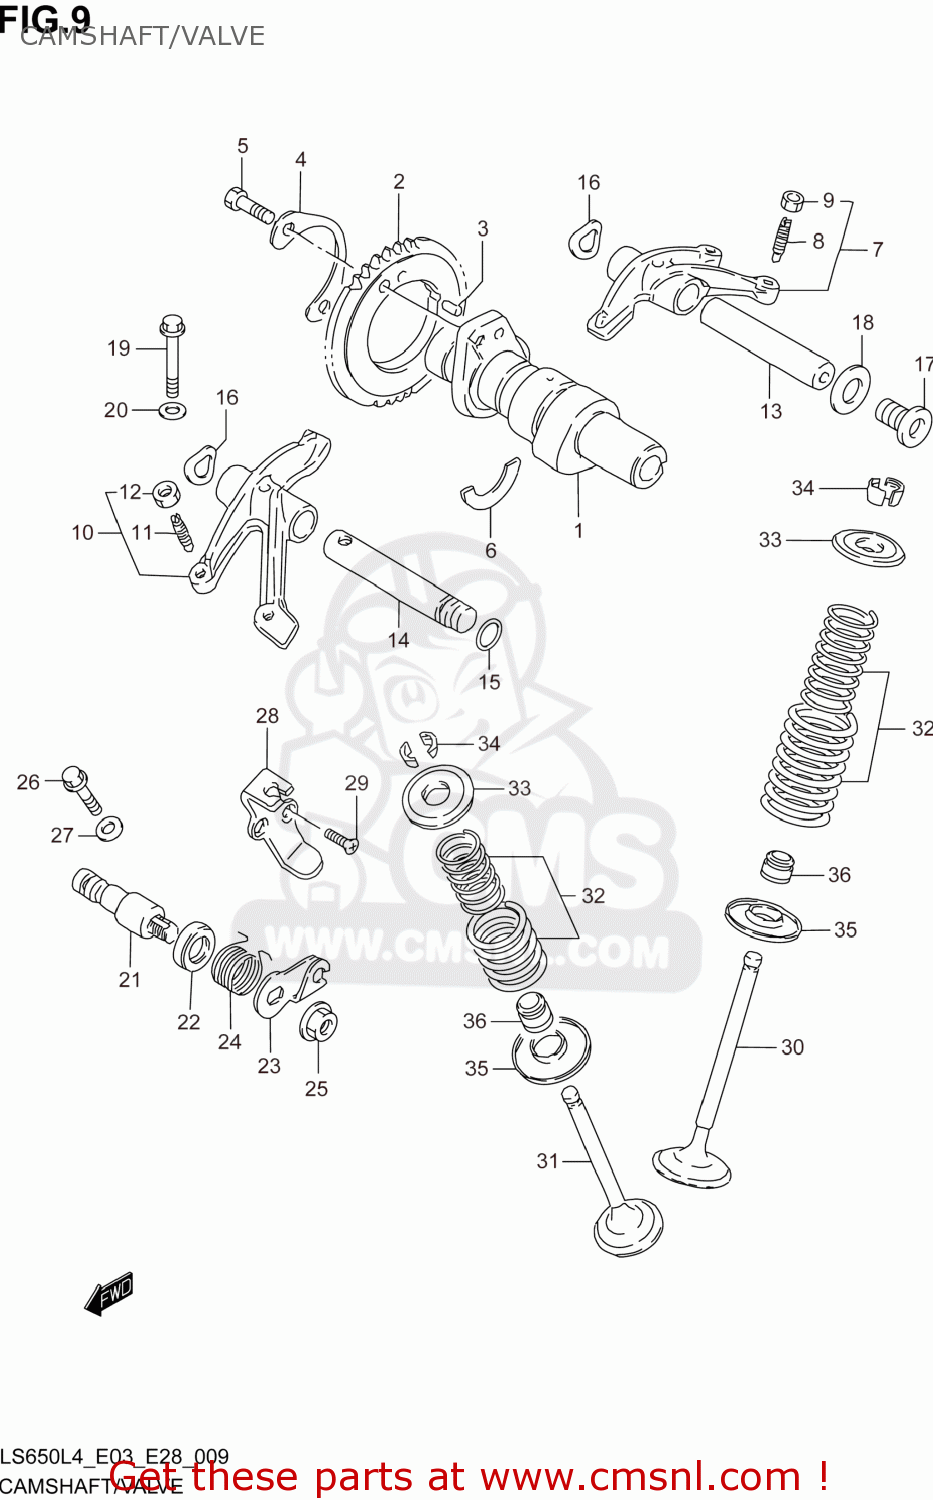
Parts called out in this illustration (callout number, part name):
1	CAMSHAFT
2	SPROCKET,CAMSHAFT
3	PIN(5X12.9)
4	WASHER,SPROCKET
5	BOLT(6X16)
6	C RING
7	ARM,INTAKE VALVE ROCKER
8	SCREW,TAPPET ADJUSTING
9	NUT,ADJUSTING SCREW
10	ARM,EXHAUST VALVE ROCKER
11	SCREW,TAPPET ADJUSTING
12	NUT,ADJUSTING SCREW
13	SHAFT,VALVE ROCKER ARM INTAKE
14	SHAFT,EXHAUST VALVE ROCKER ARM
15	O RING(D:1.9,ID:8.6)
16	WASHER
17	PLUG,14X12
18	GASKET(13.8X18.8X4.8) (NAS)
19	SCREW
20	GASKET(5.8X13X1.2) (NAS)
21	SHAFT,DECOMP,L
22	SEAL,OIL(10X20X6)
23	LEVER,DECOMP SHAFT,L
24	SPRING
25	NUT
26	BOLT(6X16)
27	GASKET(5.8X13X1.2) (NAS)
28	HOLDER,DECOMP CABLE,L
29	SCREW
30	VALVE,INTAKE
31	VALVE,EXHAUST
32	SPRING SET,VALVE
33	RETAINER,VALVE SPRING
34	COTTER,VALVE
35	SEAT,VALVE SPRING
36	SEAL,OIL(7X14.4X9)
